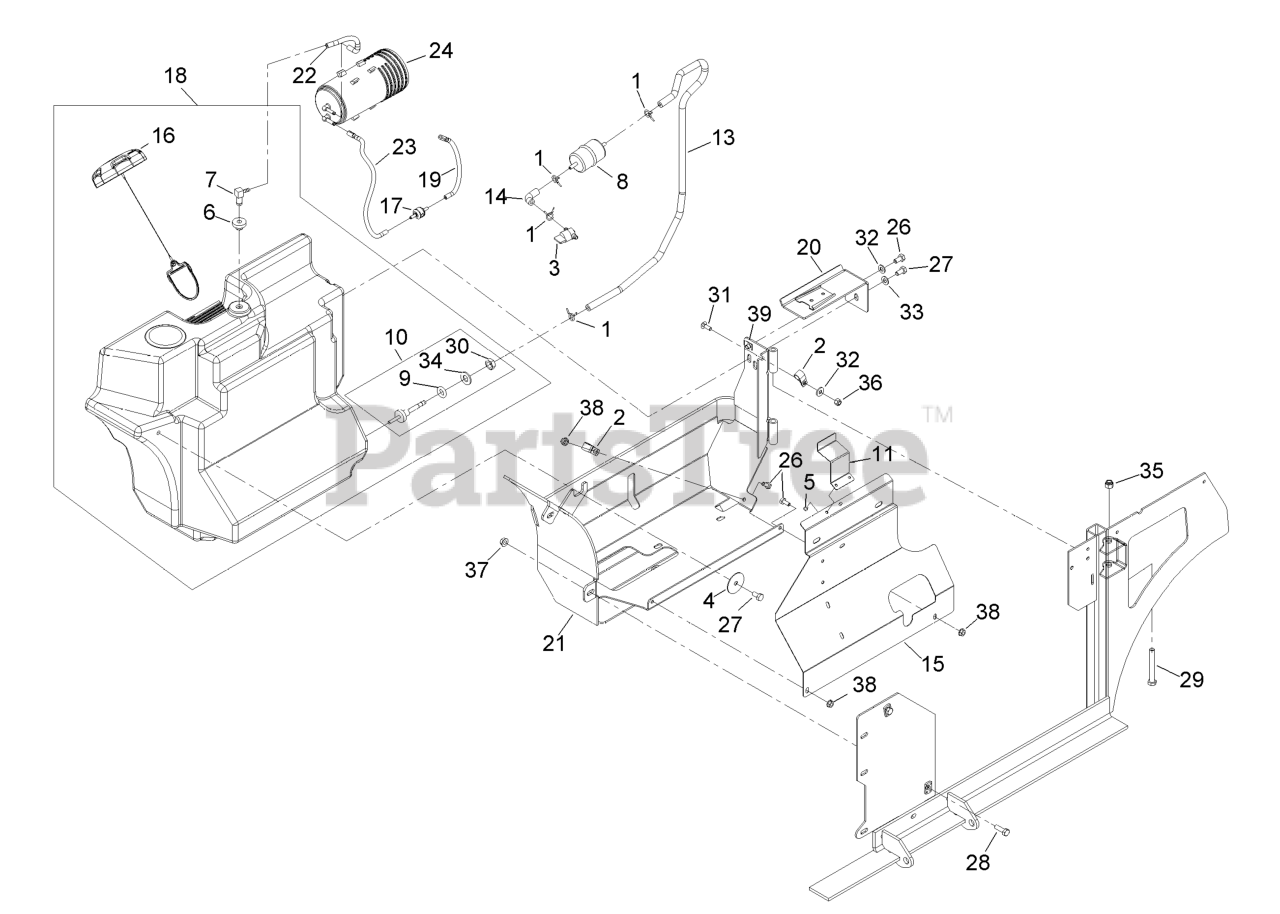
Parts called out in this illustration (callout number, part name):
2	CLIP-LOOM
3	VALVE-FUEL
5	RIVET-POP
6	BUSHING
8	Part No. 2405010 Fuel Filter
9	O-RING,BULKHEAD FITTING
10	FITTING-FUEL, BULKHEAD
11	Bracket-Tank Shield
13	HOSE-FUEL
14	HOSE-FUEL
18	ASM-FUEL TANK
19	HOSE-VENT, FORMED
21	Asm, Tank Frame
22	HOSE-VENT, FORMED
23	HOSE-VENT, FORMED
24	CANISTER-CARBON, 800CC
26	SCREW-HH
27	SCREW-HH
28	SCREW-HH
29	SCREW-CARR
30	NUT-JAM
31	BOLT-CARR
32	WASHER-FLAT
33	WASHER-PLAIN
34	WASHER-FLAT
35	NUT-LOCK, NI
36	NUT-LOCK, NI
39	Nut-Retainer-Panel 1/4-20
